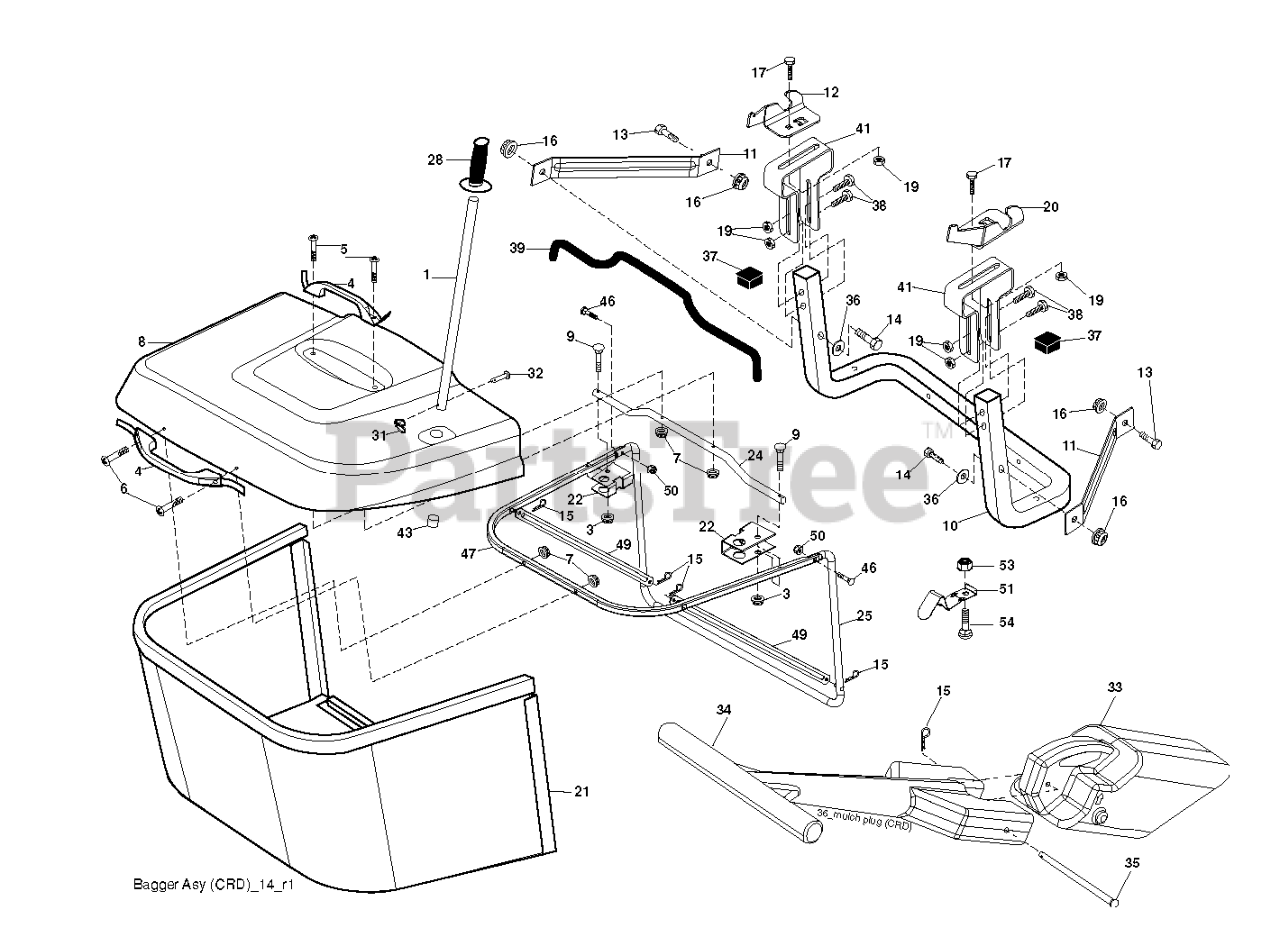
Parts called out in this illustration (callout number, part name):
1	TUBE HANDLE
3	NUT T
4	HANDLE.BAGGER.W/LVRS.BLK.CRD
5	SCREW.PAN.HEAD
6	REPL BY 532 75 00-29
8	COVER.PNT.BGR.CRD.WSLOTS.MS668
9	Bolt Carriage 1/4-20 x 2.25d x Gr.5
10	TUBE
11	BRACKET.SUPPORT.UPPER.BAG.CRD
12	BRKT PIVOT
14	BOLT-HEX EAK
15	RETAINER-SPRNG RB
16	NUT LOCK FLG 3/8-16 UNC
17	RP BOLT 5/16-18 X3/4 ZN/YEL GR
19	NUT LOCK HEX FLANGE 5/16-18
20	BRKT.PIVOT.RH.CRD
21	BAGGER.ASM.CRD.2007
22	BRKT.SIDE.BAG.CRD
24	TUBE.PIVOT.BAG.CRD.BLACK
25	PIPE
28	GRIP.HANDLE.BLACK
31	RETAINER CLIP
32	RIVET,DRILLED
33	PLUG.MULCHER.92 CRD
34	HANDLE.MULCHER.92.CRD (2 2)
36	WASHER
37	Plug Support Bagger CRD
38	BOLT.5/16-18X2.5
39	SEAL.BAGGER.CRD
41	BRKT.VERT.ADJ.BAGGER.CRD
43	PLUG, TUBING END
46	BOLT.CARRIAGE.5/16-18
47	PIPE
49	ROD
50	NUT.71038.31-18.HEX.NYLOCK
51	LATCH
53	NUT
54	BOLT
